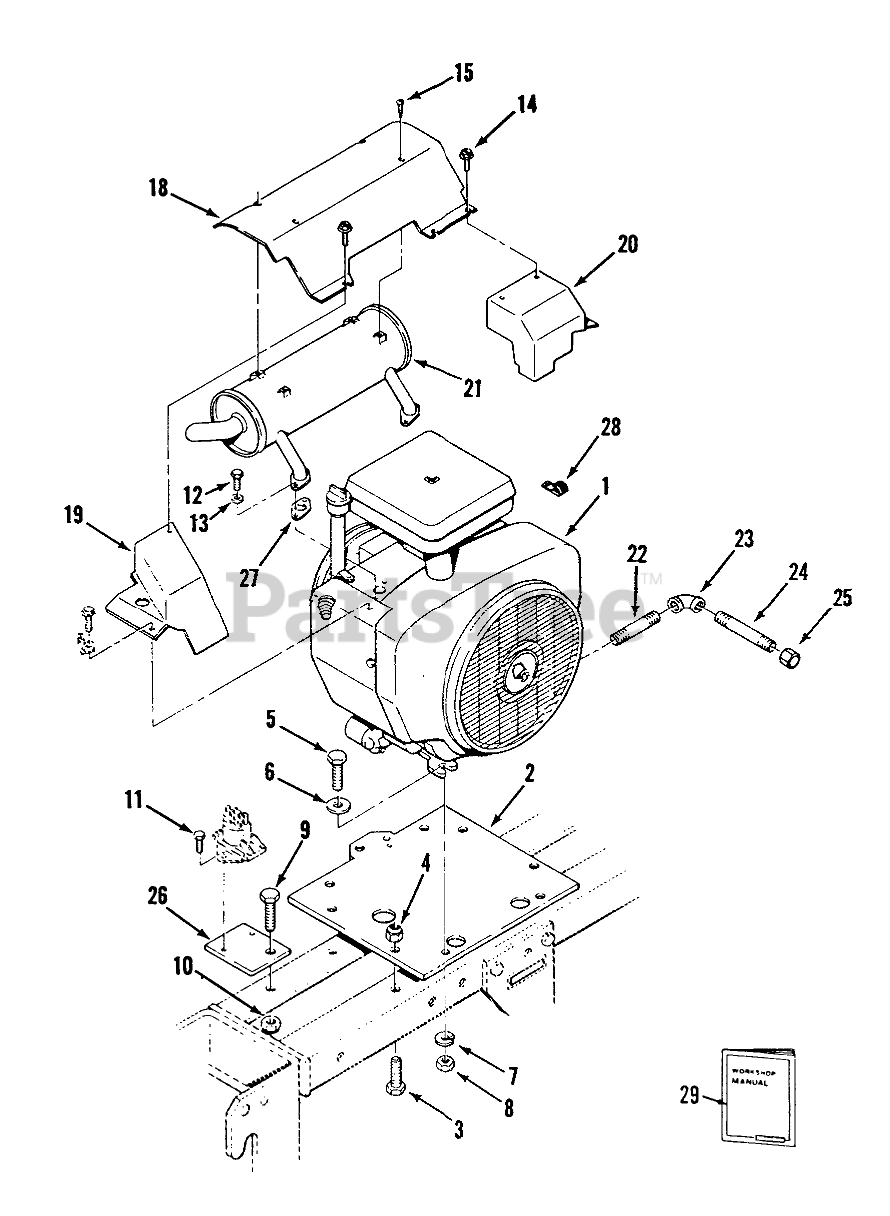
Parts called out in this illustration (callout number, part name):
2	Engine Plate
3	BOLT
4	NUT
5	BOLT
6	Washer
7	LOCKWASHER
8	Nut
9	BOLT
10	NUT
11	S.T. Bolt 1/4-20 x 1/2
12	Bolt
13	Lockwasher
14	HEX WASHER HD SCREW
15	Screw
18	Air Deflector
19	LH Exhaust Cover
20	RH Exhaust Cover
21	Muffler
22	Pipe
23	ELBOW 3/8 90 DEG
24	PIPE-NIPPLE 3/8 X 4"
25	Cap
26	PLATE-RELAY MOUNT B
27	Exhaust Gasket
28	J-CLIP
29	Onan Performer Twin Cylinder Service Manual
